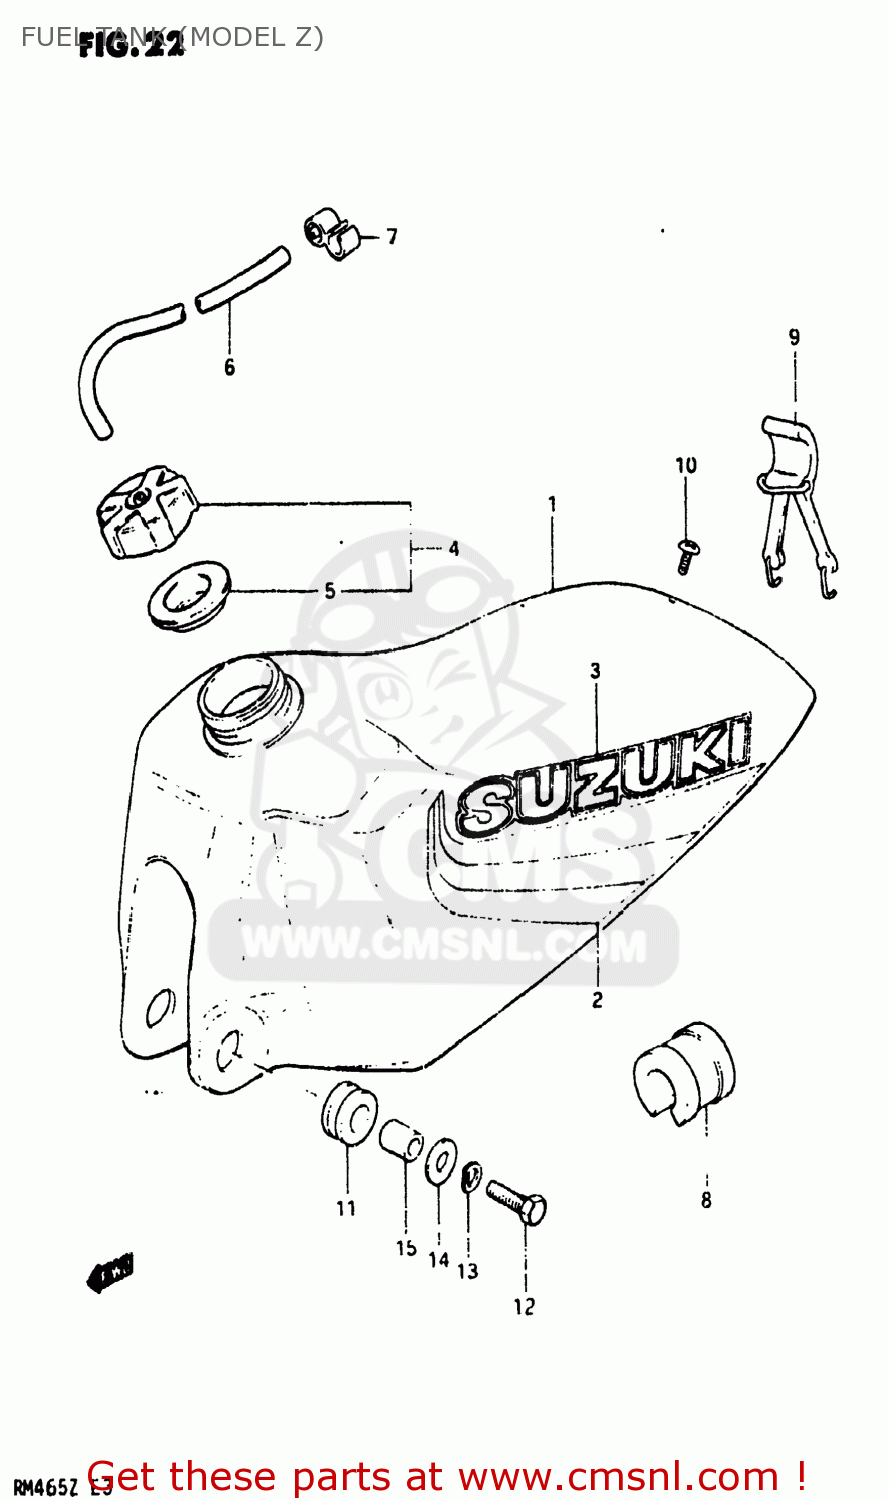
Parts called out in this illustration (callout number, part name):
1	TANK ASSEMBLY,FUEL
2	TAPE SET,FUEL TANK
3	EMBLEM
4	CAP SET,FUEL TANK
5	GASKET,FUEL TANK CAP (NAS)
6	HOSE
7	CLAMP,BREATHER HOSE
8	CUSHION,FUEL TANK UPR
9	BAND,FUEL TANK,REAR
10	SCREW (6X15)
11	CUSHION
12	BOLT
13	LOCK WASHER
14	WASHER
15	SPACER (8.8X12X13.5)
